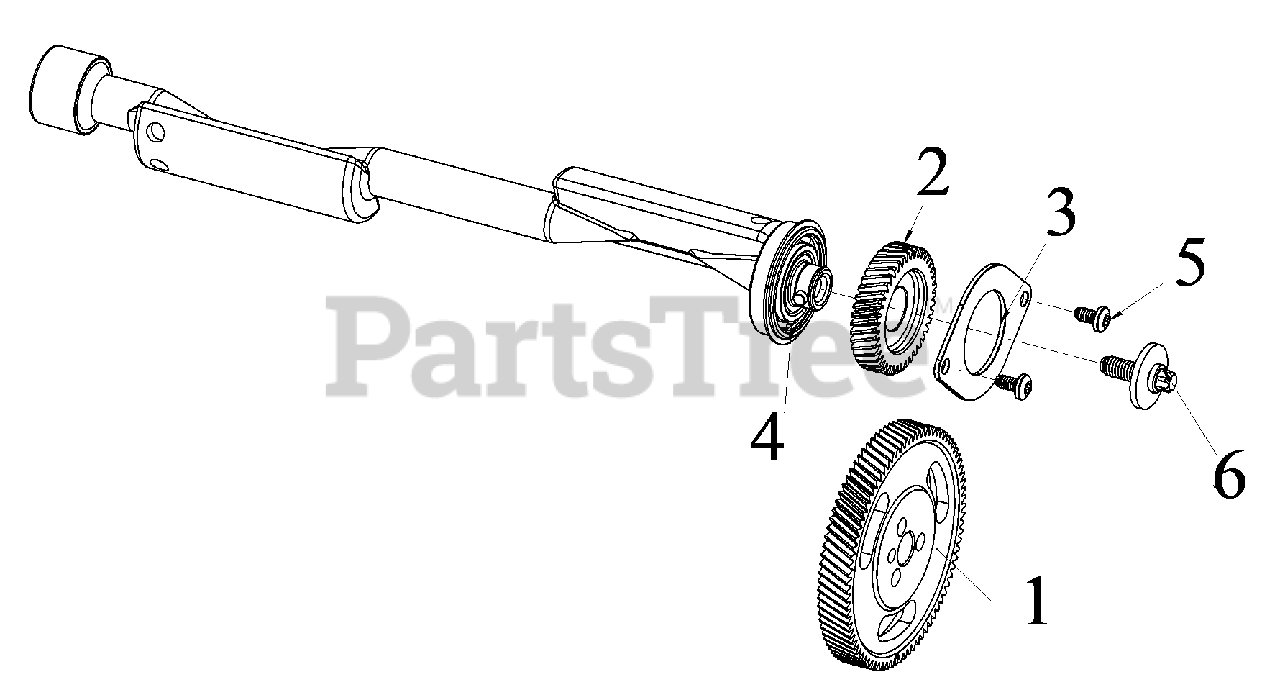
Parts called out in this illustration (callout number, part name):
1	GEAR, BALANCER SHAFT DRIVE
2	GEAR, BALANCER SHAFT DRIVE
3	RETAINER, BALANCER SHAFT
4	BALANCER SHAFT
5	BOLT, BALANCER SHAFT
6	BOLT
